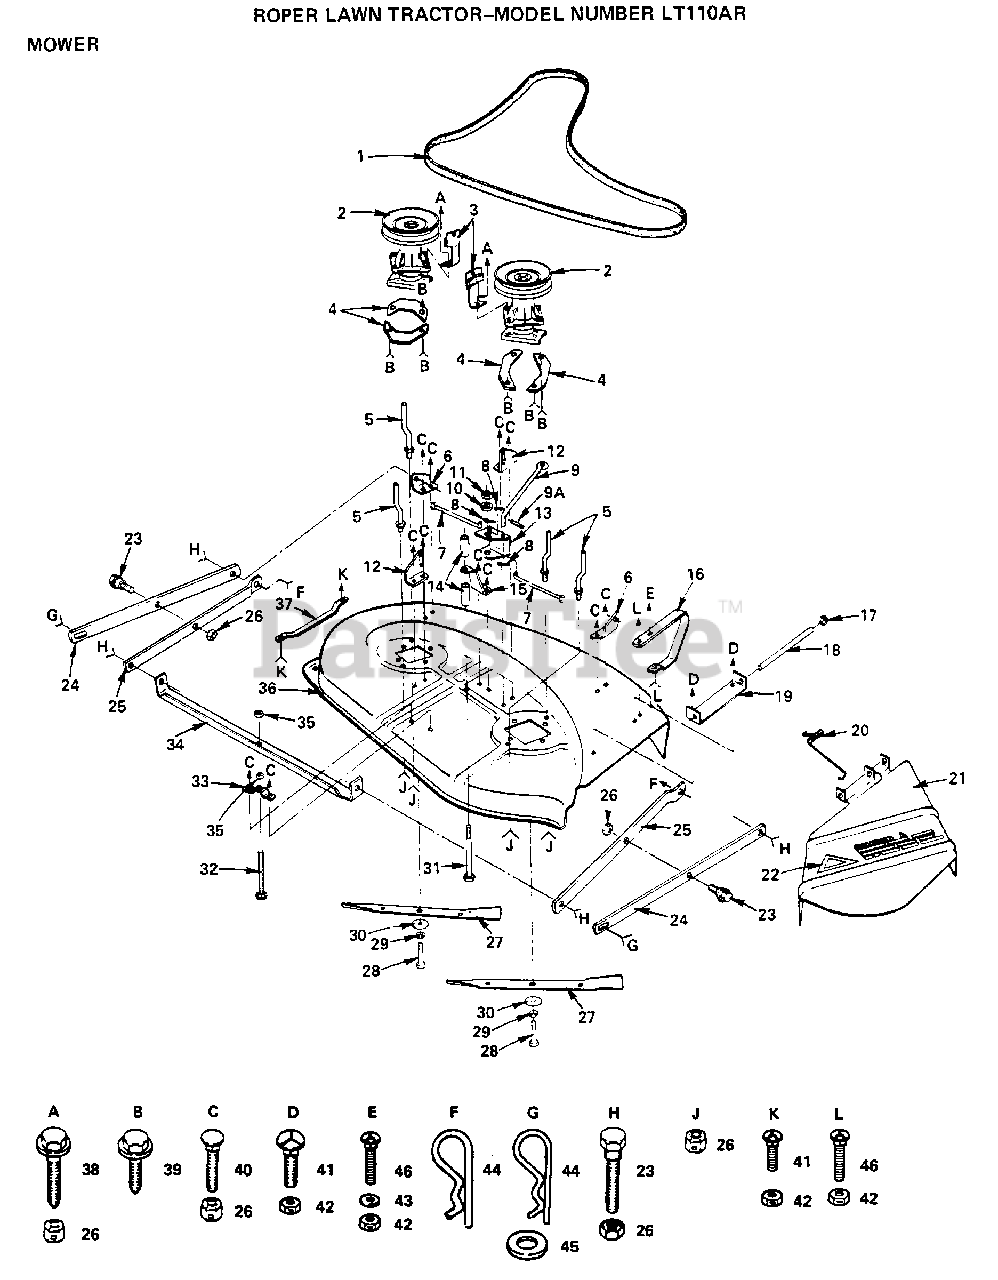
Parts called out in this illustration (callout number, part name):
4	SUPPORT PLATE LT
5	BELT KEEPER LT
6	BRACKET FRONT LTV
7	ROD BRAKE LTV
8	COTTER PIN
9	ROD BRAKE LTV
10	WASHER
11	LOCKNUT
12	BRACKET LIFT LTV
13	BRACKET PIVOT LTV
14	SPACER BRAKE LTV
15	BRACKET SUPT LTV
18	ROD HINGE LTV
20	SPRING M
23	BOLT SHOULDER LTV
24	ARM SUSPENS. LTV
25	ARM SUSPENS. LTV
28	BOLT.3/8-24X1-1/2
29	LOCKWASHER
30	WASHER
34	CROSSBAR LTV
35	NUT.HEX.3/8-16UNC
37	RUNNER-LH M
38	SCREW
39	SCREW
40	BOLT
41	BOLT
43	WASHER M
46	BOLT
